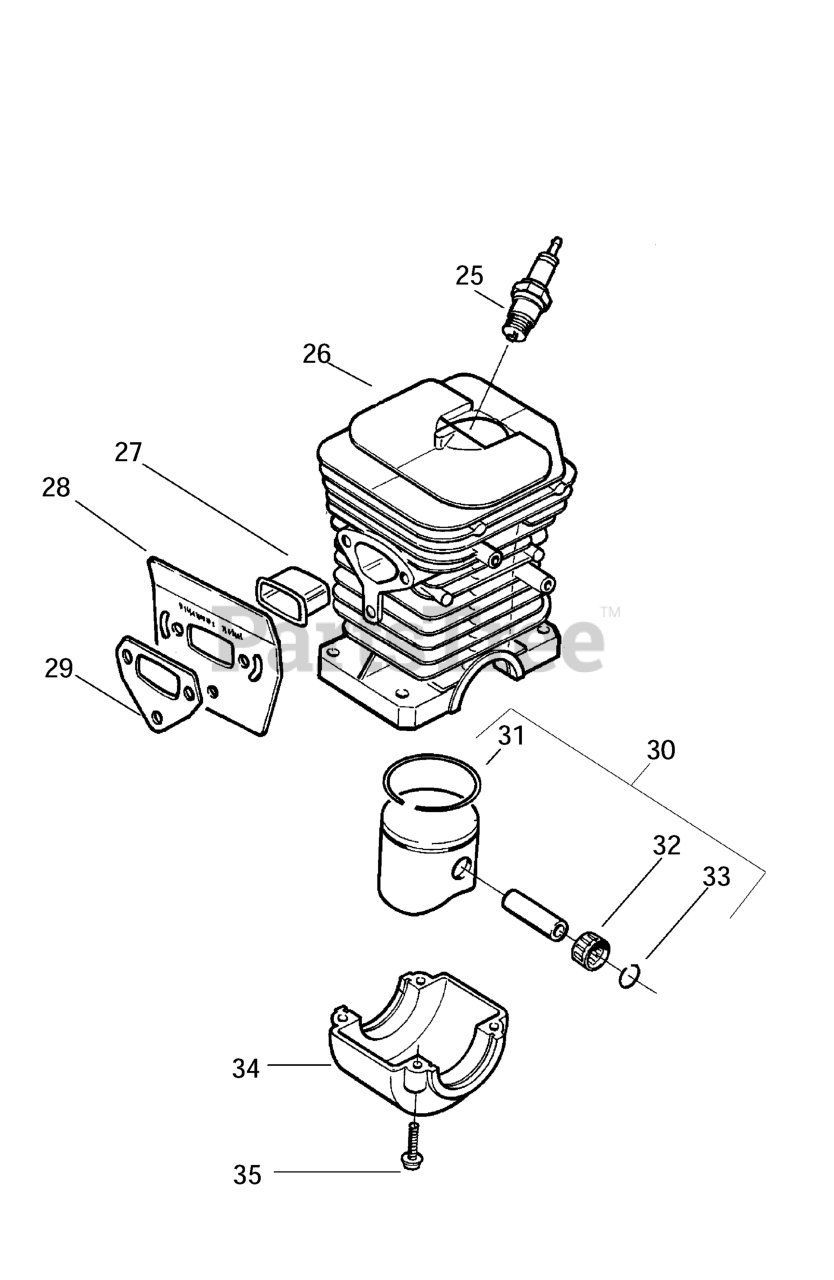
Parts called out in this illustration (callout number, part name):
25	Spark Plug (RCJ-7Y)
26	CYLINDER ASSY/136
26	CYLINDER ASSY/141
27	HEAT INSULATOR
28	MUFFLER PLATE
30	PISTON KIT/136
30	KIT-PISTON
31	PISTON RING 36
31	PISTON RING HV41
32	Piston Pin Bearing
33	C-CLIP,PSTN PIN 36/41
34	CAP-CRANKSHAFT
35	SCREW-M5-0.8 X 25MM(TAP)
